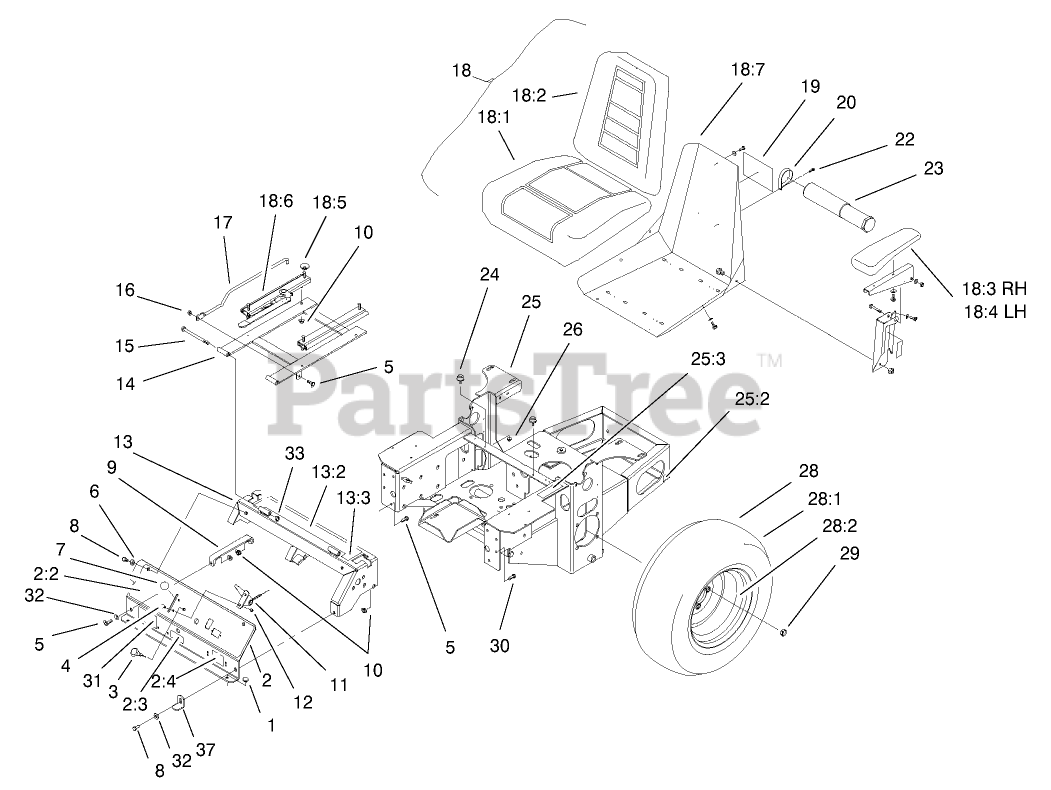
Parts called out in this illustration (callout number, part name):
1	BUMPER
2	CONTROL PANEL ASM
2:2	DECAL-PANEL, CONTROL
2:3	DECAL-VALVE, FUEL
2:4	DECAL-PROTECTION, EAR
3	CONTROL-CHOKE
4	BOLT-CARR
5	SCREW-HH
6	WASHER-PLAIN
7	KNOB-BALL
8	SCREW-HH
9	BRACKET
10	NUT-HF
11	THROTTLE CABLE ASM
12	NUT-LOCK, NI
13	CONSOLE
13:2	DECAL-CONTROL, MOTION
13:3	DECAL-BATTERY
14	FRAME-SEAT
15	SCREW-HH
16	NUT-LOCK, NI
17	ROD-RETAINER, SEAT
18	SEAT ASM
18:1	CUSHION-SEAT, BOTTOM
18:2	CUSHION-SEAT, BACK
18:3	CUSHION-ARMREST
18:4	CUSHION-ARMREST
18:5	SPACER-TRACK
18:6	TRACK-SEAT
18:7	FRAME-SEAT
19	DECAL
20	CLAMP-R
22	SCREW-HWHTF
23	TUBE-MANUAL
24	BUMPER
25	Main Frame ASM
25:2	DECAL-SURFACE, HOT
25:3	Decal-Release, Drive
26	NUT-LOCK, NI
28	WHEEL AND TIRE ASM
28:1	TIRE
29	NUT-LUG
30	SCREW-HH
31	DECAL-Z147
32	WASHER-FLAT
33	NUT-LOCK, NI
37	STOP-COVER
